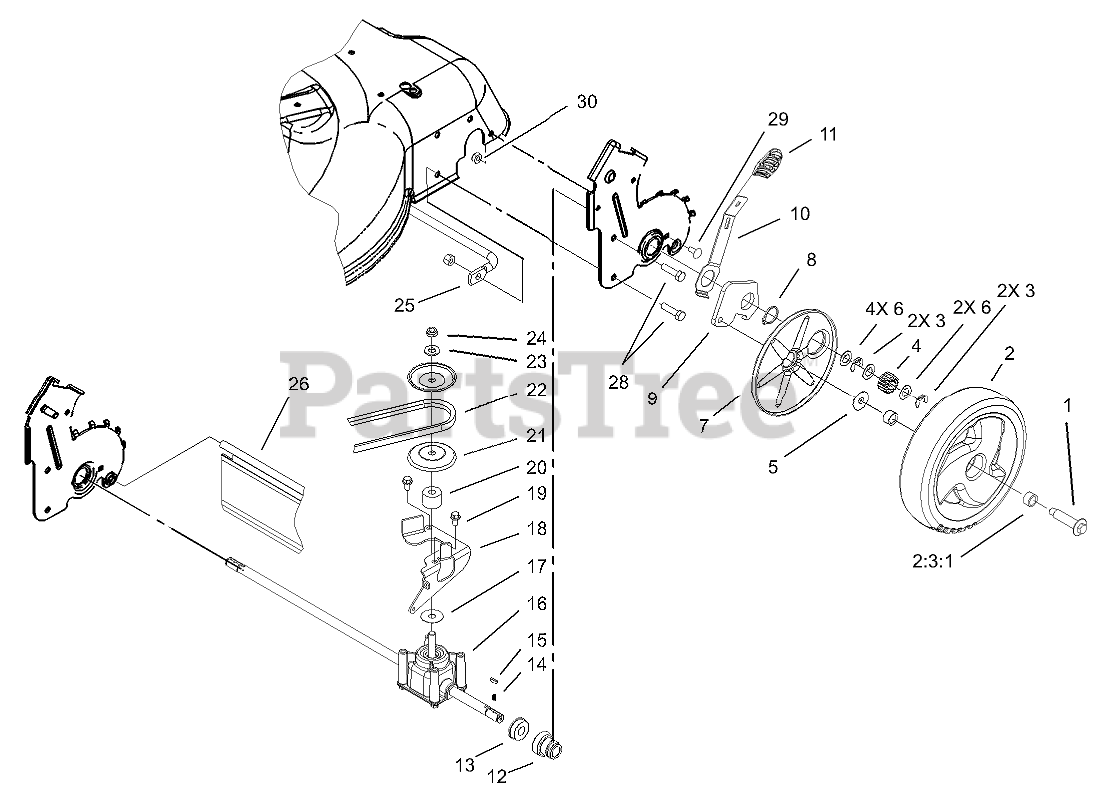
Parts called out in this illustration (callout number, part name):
1	BOLT-SHOULDER
2	Wheel Gear ASM
2:3:1	BUSHING
3	RING-CLIP, LOCKING
4	Gear-Pinion, 15t
5	WASHER-STEPPED
6	Washer-Thrust
7	COVER
8	RING-RETAINING
9	Arm-Pivot, Rear (LH)
10	Arm-Spring
11	Knob-Lever, HOC
12	RETAINER-BEARING, HOC
13	BEARING-BALL
14	SPRING-COMPRESSION
16	TRANSMISSION ASM
17	WASHER-PLAIN
18	BRACKET-PIVOT, RWD
19	SCREW-HWH
20	SPACER
21	PULLEY-HALF
22	BELT-V
23	WASHER-FLAT
24	NUT-HEX
25	BRACE-PLATE, HOC
26	Shield-Trailing
28	SCREW-HH
29	SCREW-CARR
30	NUT-LOCK, NI
